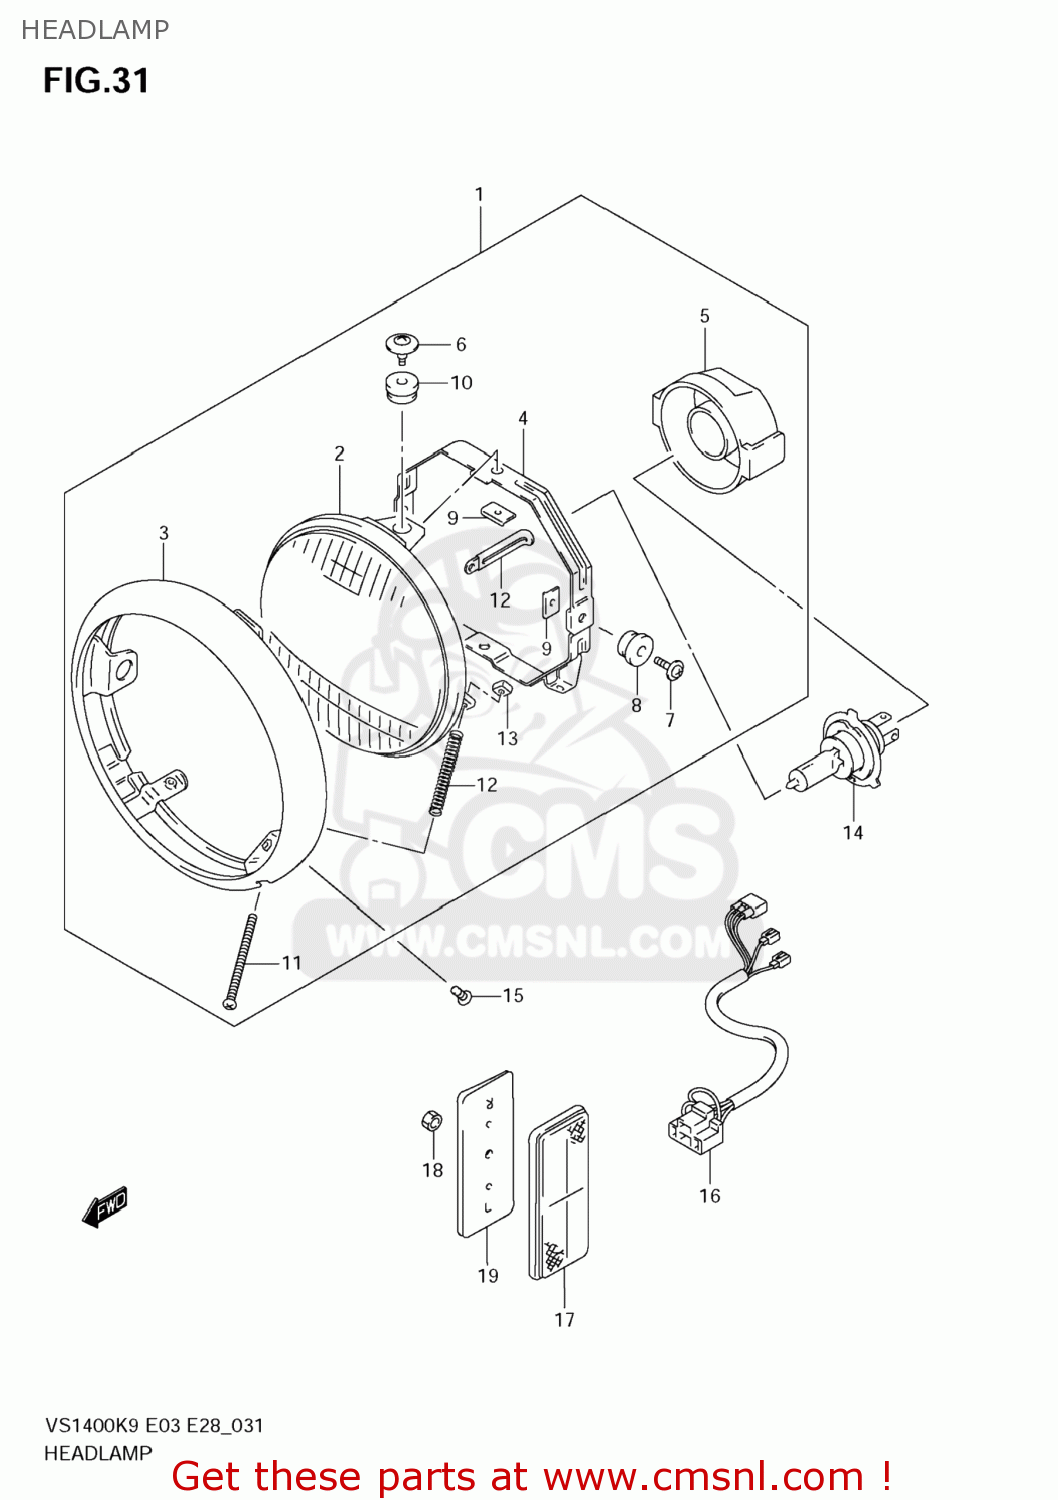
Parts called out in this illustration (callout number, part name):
1	HEADLAMP ASSY
2	UNIT,LAMP
3	RIM
4	RING,MOUNTING
5	COVER
6	SCREW
7	SCREW,MOUNTING
8	CUSHION
9	NUT
10	CUSHION
11	SCREW,ADJUSTING(4X50)
12	SPRING
13	NUT,HEADLAMP ADJUST
14	BULB(12V60/55W,H4)
15	SCREW(5X12)
16	WIRE,HEADLAMP LEAD
17	REFLEX REFLECTOR,FR SIDE
18	NUT
19	SPACER,FR SIDE RR
